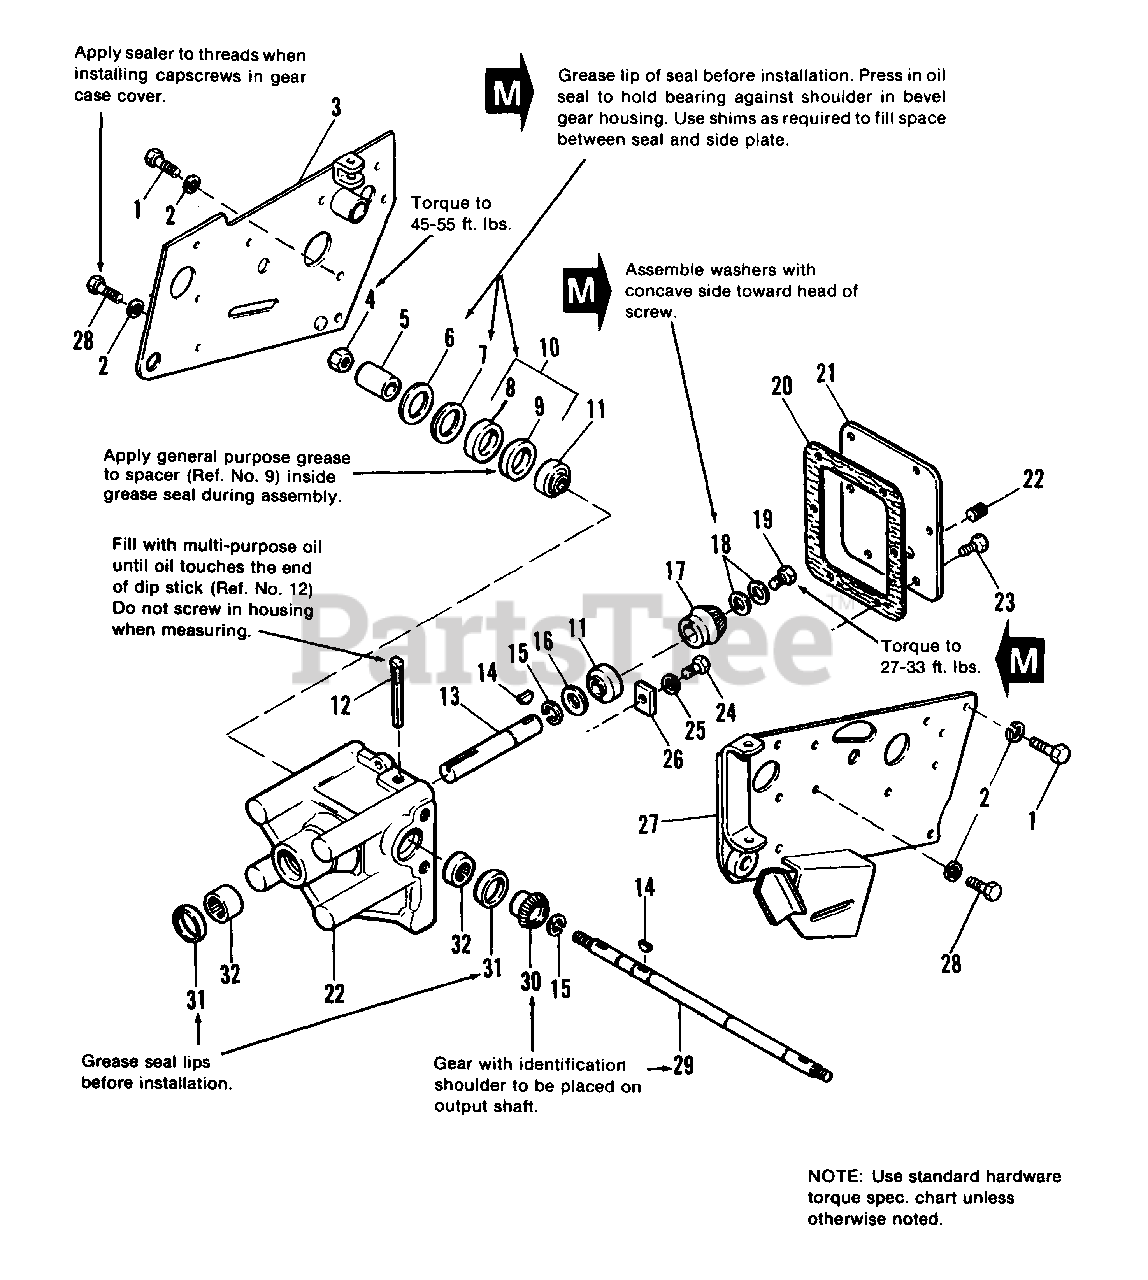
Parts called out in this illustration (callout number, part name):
1	CAPSCREW, Hex Hd., 7/16-14 x 1-1/4
2	LOCKWASHER, 7/16
3	PLATE ASSY., Side, R.H.
4	LOCKNUT, Hex, Jam, 3/4-16
9	SPACER, Oil Seal
10	SEAL KIT, Oil
11	BEARING, Ball
13	SHAFT, Driver
14	KEY, Woodruff, #9
15	RING, Retaining
17	GEAR, Bevel, Driver
19	CAPSCREW, Hex Hd., 5/16-18 x 3/4
22	PLUG, Pipe (If Equipped)
23	CAPSCREW, Hex Hd., 1/4-20 x 5/8
24	CAPSCREW, Hex Hd., 5/16-18 x 5/8
25	LOCKWASHER, 5/16
26	PLATE, Bearing, Clamp
27	PLATE ASSY., Side, LH
28	CAPSCREW, Hex Hd., 7/16-14 x 1
29	SHAFT, Driven
30	GEAR, Bevel, Driven
32	BEARING, Needle
33	HOUSING, Bevel Gear
